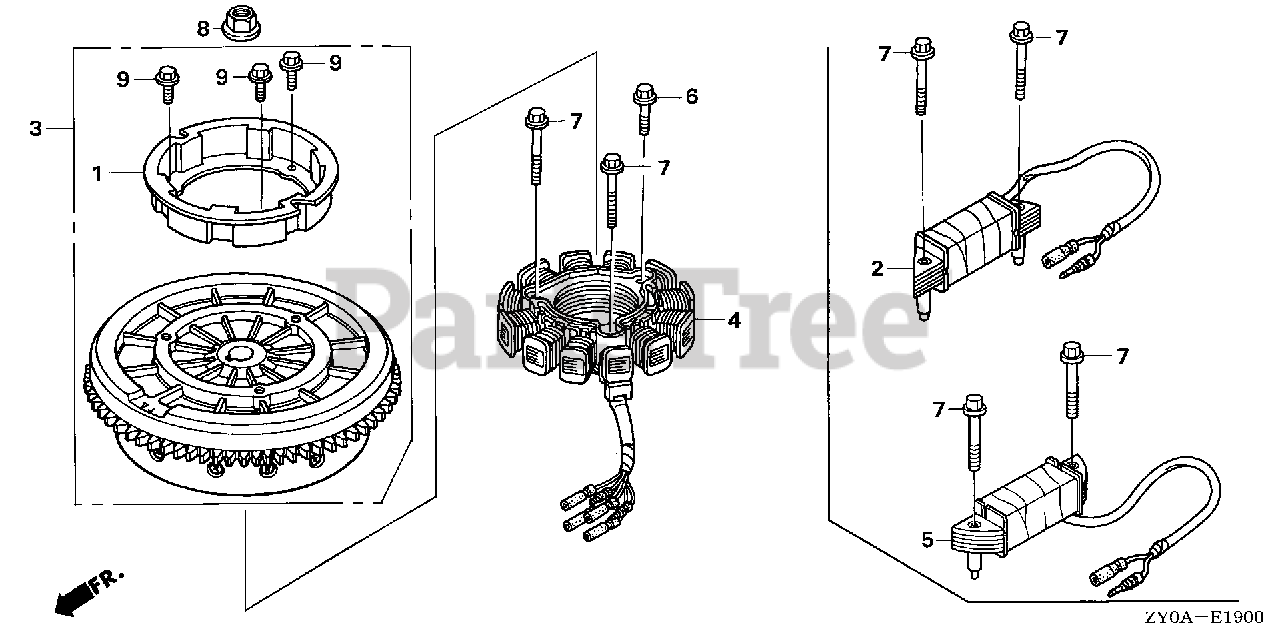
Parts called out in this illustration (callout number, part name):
1	PULLEY, STARTER
3	FLYWHEEL *TBLACK* (SELF STARTER) (BLACK)
4	COIL ASSY., CHARGE (12A)
6	BOLT, FLANGE (6X36) (CT200)
7	BOLT, FLANGE (6X52) (CT200)
8	NUT, SPECIAL (16MM)
9	BOLT, FLANGE (6X10)
